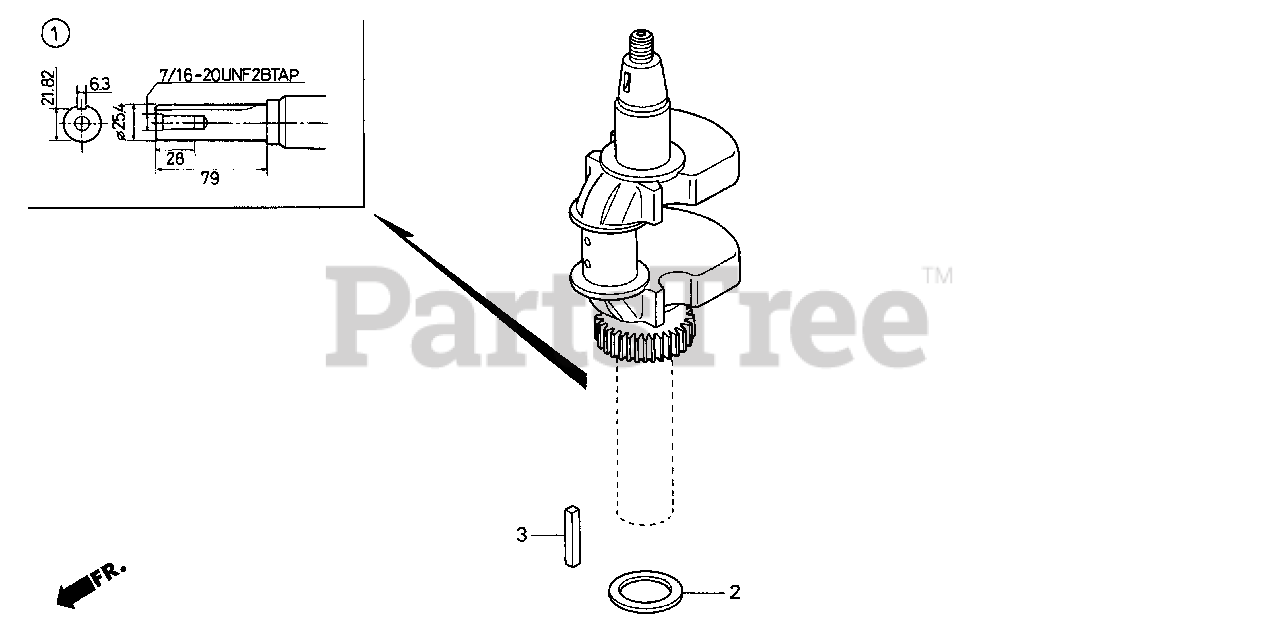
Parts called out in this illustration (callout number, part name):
1	CRANKSHAFT
2	WASHER, CRANKSHAFT THRUST
3	KEY (6.3X6.3X43)
